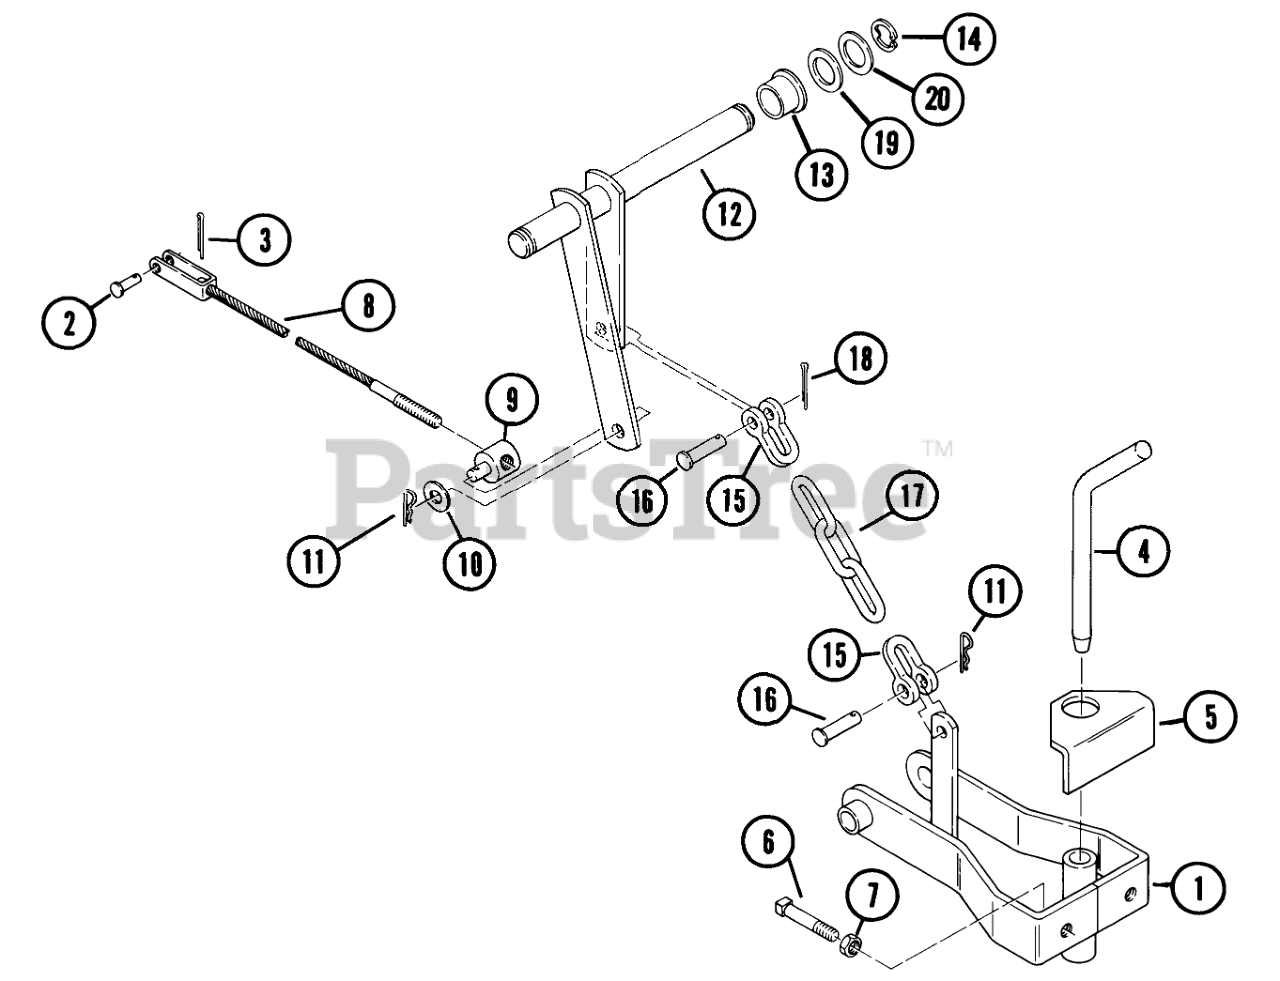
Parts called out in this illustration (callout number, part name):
1	Hitch Assembly
2	Pin
3	Cotter Pin
4	Hitch Pin
5	PLATE ADJ HITCH R
6	SCREW
7	Jam Nut
8	ASSY-LIFT CABLE
9	TRUNNION-CLUTCH ROD
10	Washer
11	Hairpin
12	Lever Assy.
13	BUSHING
14	E-RING
15	Clevis
16	Clevis Pin
17	Lift Chain
19	WASHER
20	WASHER-SHIM
